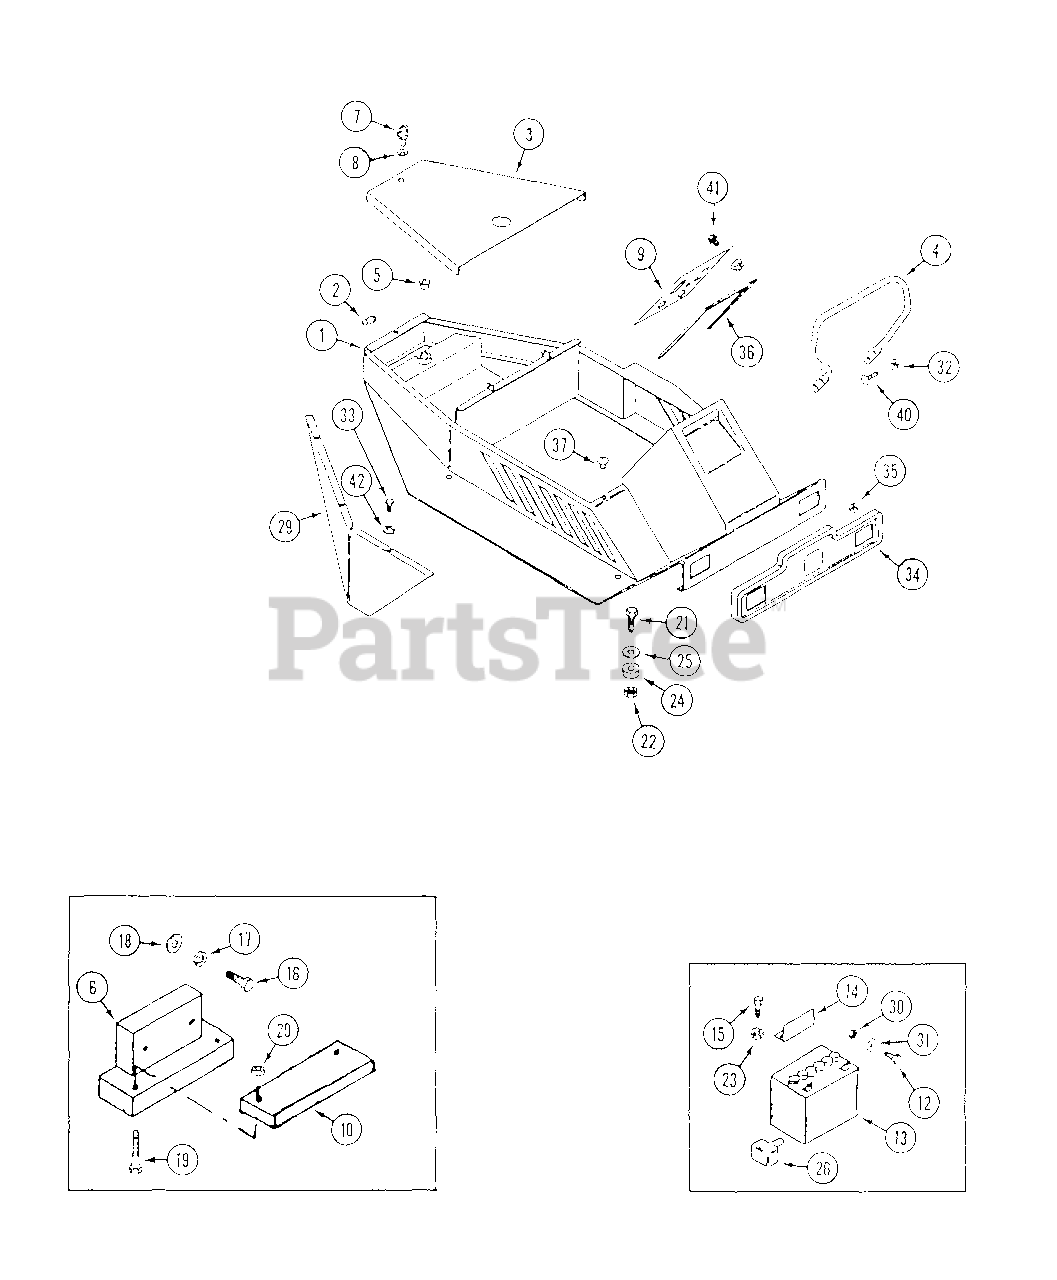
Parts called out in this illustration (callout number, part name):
1	BODY
2	FITTING - grease
5	BEARING - rear wheel fork
6	WEIGHT - tail
7	STUD - fastener
8	GROMMET - fastener
10	WEIGHT - tail 13 lb.
12	BOLT - 1/4" - 20 x 3/4"
13	BATTERY - 12V, 300 CCA
14	BRACKET - hold down, battery
15	BOLT - 1/4" - 20 x 7"
16	BOLT - 5/16" - 18 x 1"
17	LOCKWASHER - 5/16"
18	WASHER - 5/16"
19	BOLT - 3/8" - 16 x 4-1/2"
20	NUT - 3/8" - 16 flange lock
21	BOLT - 1/2" - 13 x 3"
22	NUT - 1/2" lock
23	NUT - 1/4" - 20 lock
24	MOUNT - body, rubber
25	WASHER - mount, body
26	COVER - terminal
30	NUT - 1/4" - 20
31	WASHER - 1/4"
32	NUT - 5/16" - 18 flange lock
33	BOLT - 1/4" - 20 x 3/4" self-tap
35	NUT - #8 - 32 flange lock
36	TRIM - 28"
37	BUMPER - nylon
40	BOLT - 5/16" - 18 x 5/8"
41	SCREW - #12 x 1/2"
42	LOCKWASHER - 1/4"
